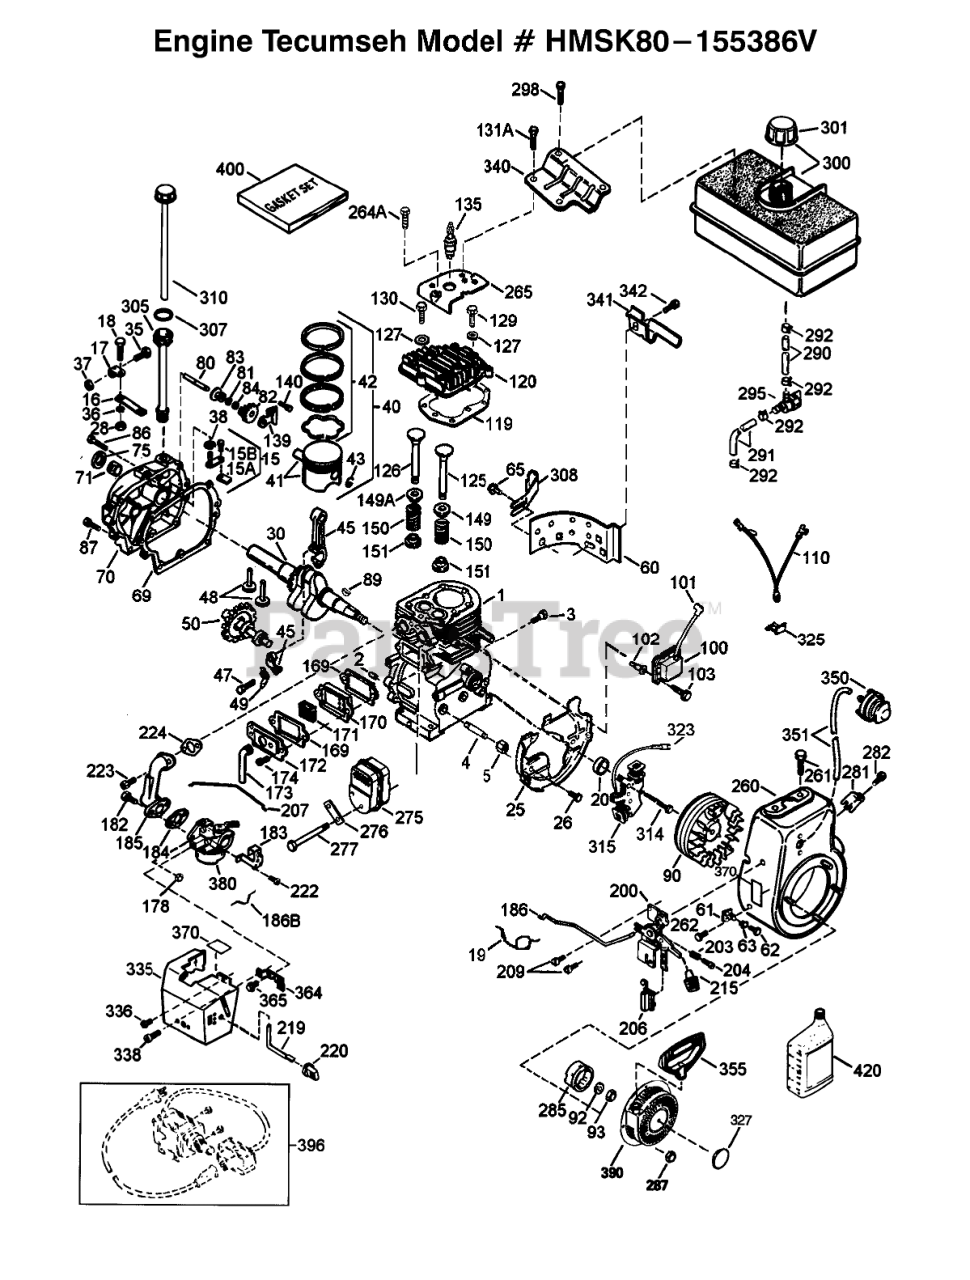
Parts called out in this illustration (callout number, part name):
1	Cylinder Asm (Incl. Ref. #2, 20, & 72)
2	Pin-Dowel
3	Screw (1/4-20x1/2)
4	Nipple-Pipe
5	Cap-Pipe
15	Governor (Incl. Ref. #15A & 15B)
15A	Yoke-Governor
15B	Screw (6-40x5/16)
16	Lever-Governor
17	Clamp-Lever, Governor
18	Screw (T-15, 8-32x7/16)
19	Spring-Throttle
20	Seal-Oil
25	Baffle-Housing, Blower
26	Screw (1/4-20x19/32)
28	Nut-Lock
30	Crankshaft
35	Screw
36	Washer-Lock
37	Nut-Lock
38	Ring-Retaining
40	Piston-Pin and Ring Set (STD)
40	Piston- Pin and Ring Set (.010 O S)
41	Piston & Pin Asm (Std.)(Incl. Ref. #43)
41	Piston & Pin Asm (.010" OS)(Incl. Ref. #43)
42	Ring Set (STD)
42	Ring Set (.010 O S)
43	Ring-Retaining, Piston Pin
45	Connecting Rod Asm (Incl. Ref. #47, & 49)
47	Bolt-Rod, Connecting
48	Lifter-Valve
49	Dipper-Oil
50	Camshaft (MCR)
60	Extension-Housing, Blower
61	Bracket
62	Screw (8-32 x 3/8)
63	Grommet
65	Screw
69	Gasket-Cover, Cylinder
70	Cylinder Cover (Incl. Ref. #71, 75, & 80)
71	Bushing-Crankshaft
72	Plug-Drain, Oil (SQH 1/4-18)
75	Seal-Oil
80	Shaft-Governor
81	Washer-Flat
82	Governor Gear Asm (Incl. Ref. #81)
83	Spool-Governor
84	Ring-Retaining
86	Screw (1/4-20x1-3/16)
87	Screw (1/4-20x1-11/16)
89	Key-Flywheel
90	Flywheel ASM
92	Washer-Belleville
93	Nut-Flywheel
100	Solid State ASM
101	Cover-Spark Plug
102	Stud-Mounting, Solid State
103	Screw (T-15, 10-24 x 15/16)
110	Ground Wire
119	Gasket-Head, Cylinder
120	Head-Cylinder
125	Exhaust Valve (Std.)(Incl. Ref. #151)
125	Exhaust valve (1/32" OS)(Incl. Ref. #151)
126	Intake Valve (Std.)(Incl. Ref. #151)
126	Intake Valve (1/32" OS)(Incl. Ref. #151)
127	Washer-Flat
129	Screw (5/16-18x1-25/32)
130	Screw (5/16-18x1-1/2)
131A	Screw
135	Spark Plug-Resistor (R J19 L M)
139	Bracket-Gear, Governor
140	Screw (10-24x1/2)
149	Cap-Spring, Valve
149A	Cap-Spring, Valve
150	Spring-Valve
151	Keeper-Spring, Valve
169	Gasket-Cover, Valve
170	Body-Breather
171	Element-Breather
172	Cover-Valve
173	Tube-Breather
174	Screw
178	Nut and Lock Washer (1/4-28)
182	Screw (1/4-28x1)
183	Bracket-Choke
184	Gasket-Carburetor To Intake Pipe
185	Pipe-Intake
186	Link-Governor
186B	Spring-Choke
200	Control Bracket (Incl. Ref.#19, 1
203	Spring-Compression
204	Screw (T-10, 5-40x7/16)
206	Terminal
207	Link-Throttle
209	Screw (10-32 x 1/2)
215	Knob-Control
219	Rod-Choke
220	Knob-Control
222	Screw (10-32 x 1/2)
223	Screw (T-30, 5/16-18x1-3/32)
224	Gasket-Pipe, Intake
260	Housing-Blower
261	Screw (5/16-18x3/4)
262	Screw
264A	Screw (1/2-20x5/8)
265	Cover-Cylinder Head
275	Muffler
276	Plate-Locking
277	Screw (5/16-18x4-3/16)
281	Screw
282	Screw (8-32 x 3/8)
285	Cup-Starter
287	Nut and Lock Washer (1/4-28)
290	Line-Fuel (8.62)
291	Line-Fuel
292	Clamp-Line, Fuel
295	Valve-Shut Off, Fuel
298	Screw (1/4-15x7/8)
300	Fuel Tank (Incl. Ref. #292 & 301)
301	Cap-Fuel
305	Tube-Fill, Oil
307	O-Ring
308	Clip-Tube, Fill
310	Gauge Oil ASM
314	Screw (1/4-20 x 3/4)
315	Alternator Coil (18 Watt)(Incl. Ref. #323)
323	Terminal
325	Clip-Wire
327	Plug Starter
335	Cover-Carburetor
336	Screw (10-32x1/2)
338	Screw (10-32 x 3/8)
340	Bracket-Tank, Fuel
341	Bracket-Tank, Fuel (Black)
342	Screw (1/4-20x19/32)
350	Primer-Asm
351	Line-Primer
355	Handle-Starter, Mitten Grip
364	Bracket-Carburetor
365	Screw (8-32x27/64)
370	Decal-Lubrication
380	Carburetor (Incl. Ref. #184)
390	Starter-Rewind
396	Starter-Electric (110 Volt)
400	Gasket Set
420	Oil-Engine (SAE 5W30)
